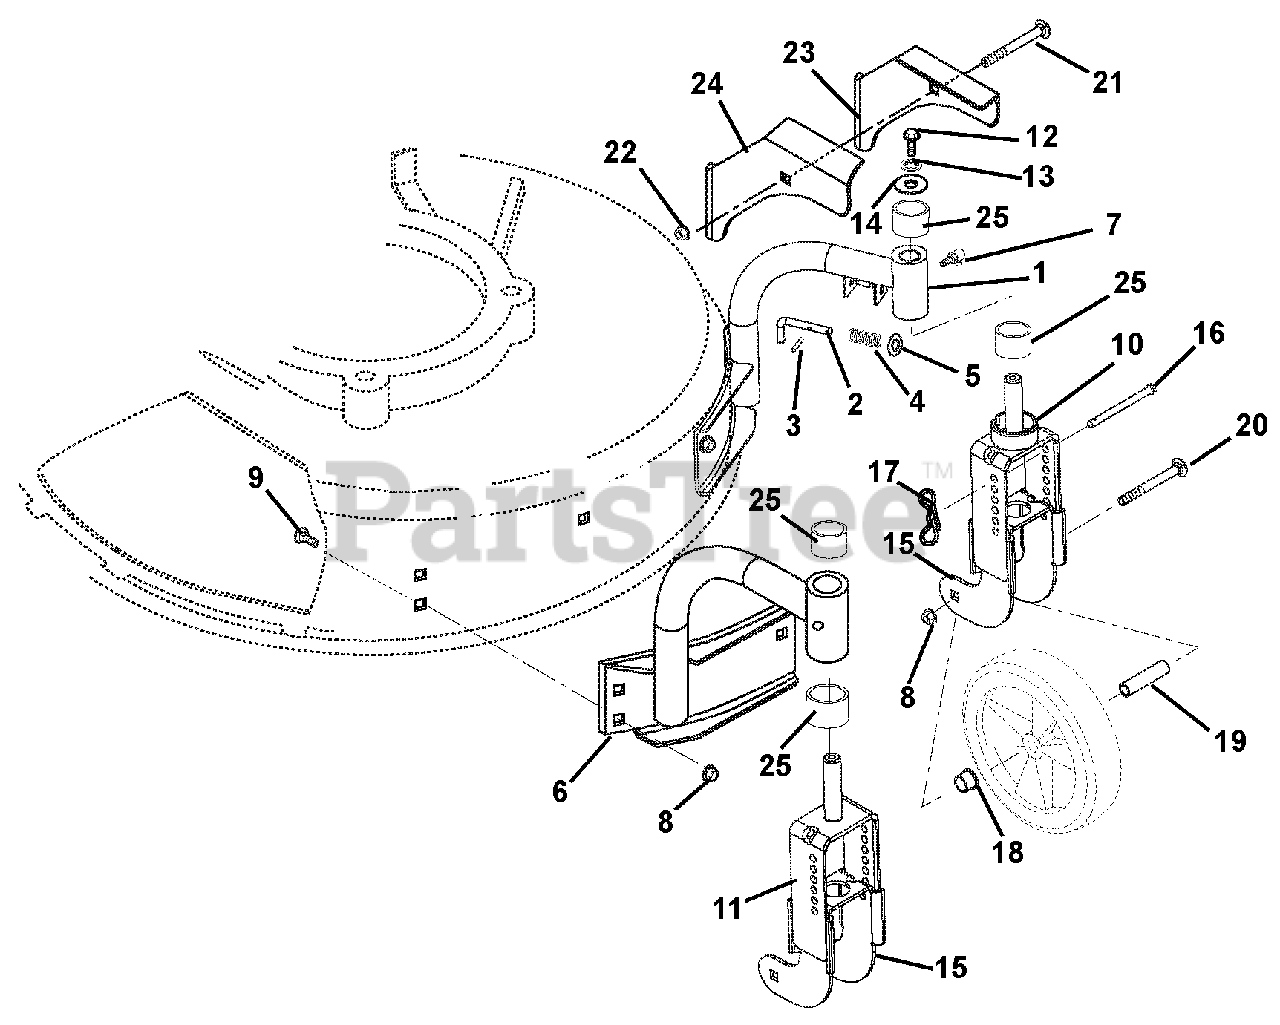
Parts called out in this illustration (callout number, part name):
1	Weldment, Left Hand Mount
2	Pin, Lockout
3	Pin, Roll .094 x .50
4	Spring, Compression - Swivel Lockout
5	Washer, Flat Steel .281 x .62 x .065
6	Weldment, Right Hand Mount
7	Fitting, Lube .25-28 x .256
8	Nut, Spin Lock Flange .312-18
9	Bolt, Round Head Square Neck .31-18 x .50 Grade 5
10	Yoke, Left Hand Outer
11	Yoke, Right Hand Outer
12	Bolt, Hex .25-20 x .75 Grade 5
13	Washer, Locking .25 x .062 Regular
14	Washer, Flat Steel .28 x 1.00 x .063
15	Yoke, Inner
16	Pin, Height Adjustment
17	Pin, Bow Tie Locking Cotter
18	Bushing, Flange .50 x .625 x .50 x .75
19	Spacer, Wheel
20	Bolt, Round Head Square Neck .31-18 x 2.75
21	Bolt, Round Head Square Neck .25-20 x 1.50 Grade 5
22	Nut, Locking Flange .25-20
23	Bracket, Hood Cable Left Hand
24	Bracket, Hood Cable Right Hand
25	Bushing, Sleeve .625x .750x .500 br
